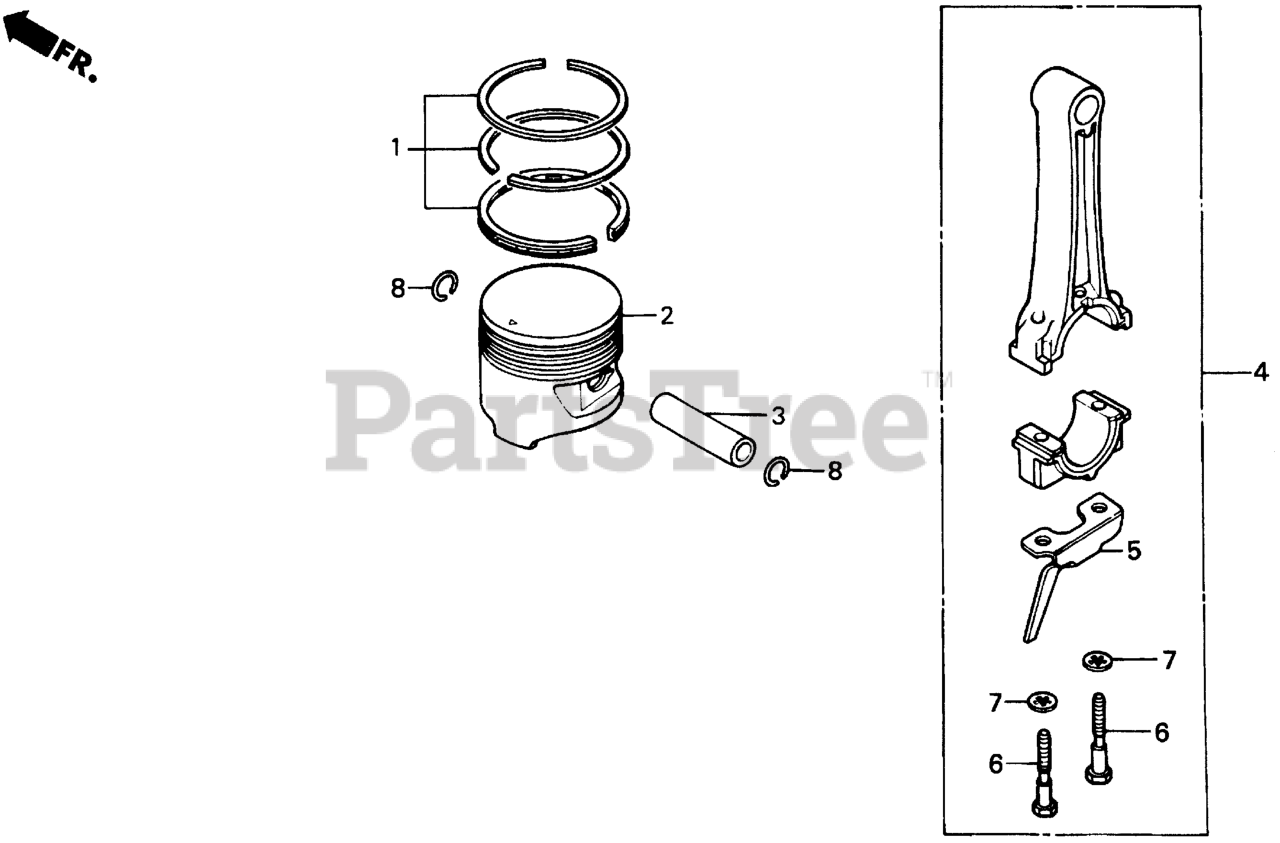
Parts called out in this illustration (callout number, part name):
1	RING SET, PISTON
1	RING SET, PISTON (STD)
1	RING SET, PISTON (OS 0.25)
1	RING SET, PISTON (OS 0.50)
1	RING SET, PISTON (0.75)
1	RING SET (0.75)
2	PISTON (STD)
2	PISTON (OS 0.25)
2	PISTON (OS 0.50)
2	PISTON (0.75)
3	PIN, PISTON
4	ROD ASSY., CONNECTING
4	ROD ASSY., CONNECTING (UNDER SIZE)
5	DIPPER, CONNECTING ROD
6	BOLT, CONNECTING ROD (7MM)
7	WASHER, LOCK (7MM)
8	CLIP, PISTON PIN (16MM)
